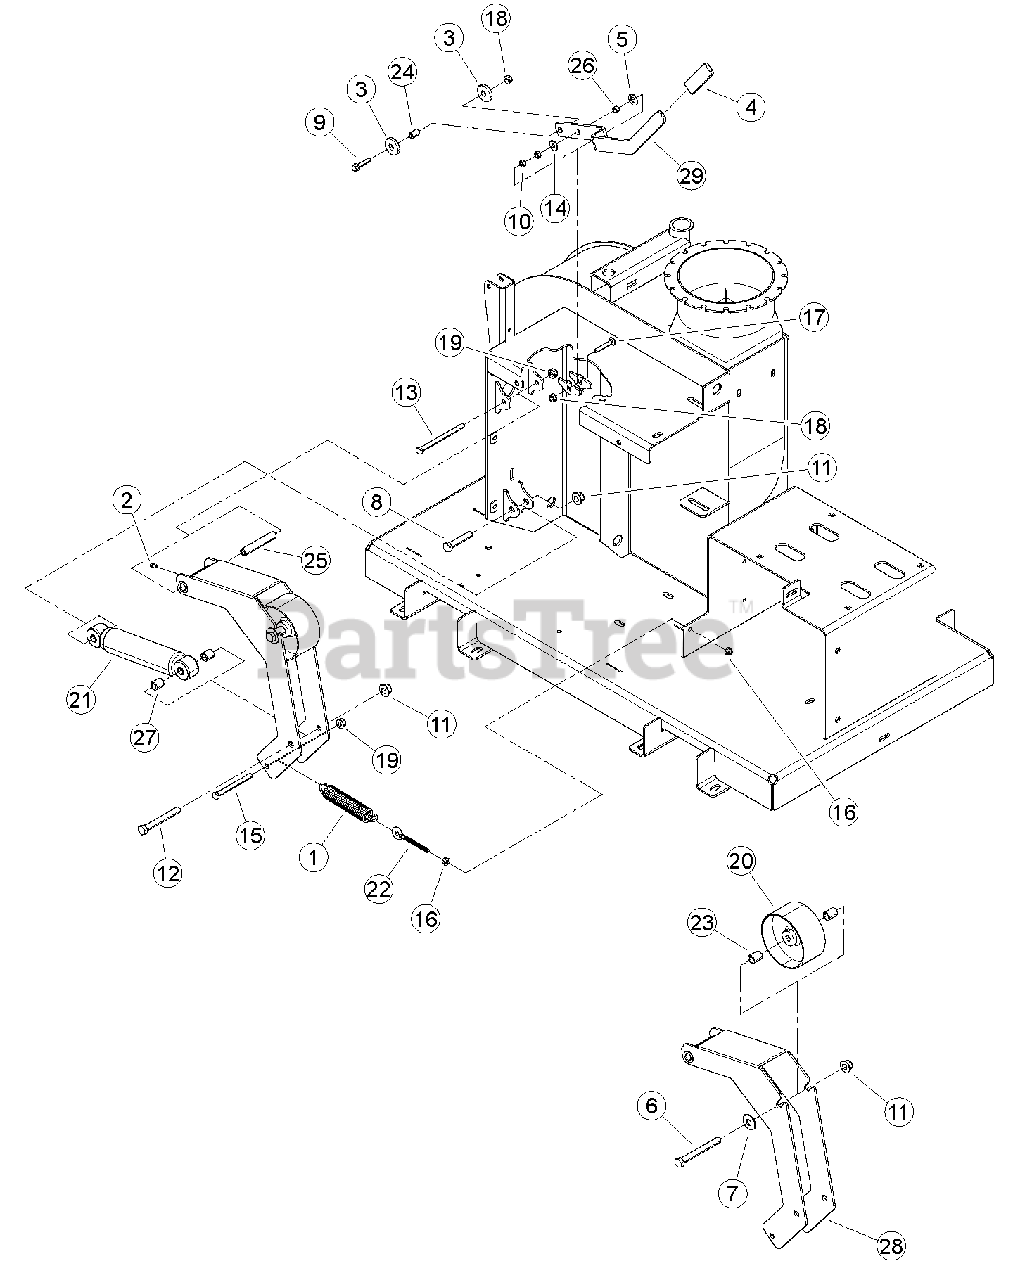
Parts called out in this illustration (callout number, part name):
1	SPRING, 9 GAUGE WIRE TENSION
2	FITTING, 1/4 SELF-TAP GREASE
3	WASHER, UHMW SPACER .515ID-1.50OD
4	GRIP, CLUTCH HANDLE
5	WASHER, 1/2 INCH NYLON
6	BOLT, 1/2 X 4-1/2" GR5 HHCS NC ZP
7	WASHER, 1/2" FLAT ZP
8	BOLT, 1/2 X 2-1/2 GR5 HEX CAP ZP
9	BOLT, 5/16 X 1-1/2 FLANGE NC
10	NUT, 5/16 HEX NC - ZP
11	NUT, 1/2-13 NYLOCK FLANGE
12	BOLT, 1/2 X 4 HEX CPS G5 ZP
13	BOLT, 3/8 X 5" GR5 HEX CPS ZP
14	WASHER, 5/16" FLAT ZP
15	BOLT, 3/8 X 4" HHCS GR5 NC ZP
16	NUT, 5/16 SERRATED FLANGE NC ZP
17	BOLT, 5/16 X 2" GR5 CRG NC ZP
18	NUT, 5/16-18 NYLOCK-FLANGE
19	NUT, 3/8-16 NYLOCK FLANGE
20	PULLEY, IDLER 5 X 2.50"
21	ABSORBER, IDLER SHOCK
22	BOLT, 5/16 X 3-5/8" EYE
23	SPACER, .75 X .90
24	SPACER, .50 X .775
25	TUBE, PIVOT
26	SPACER, 1/2 OD X 14 GA WALL X .320
27	SPACER, IDLER SHEAVE
28	WELDMENT, IDLER ARM
29	HANDLE, ENGAGEMENT
